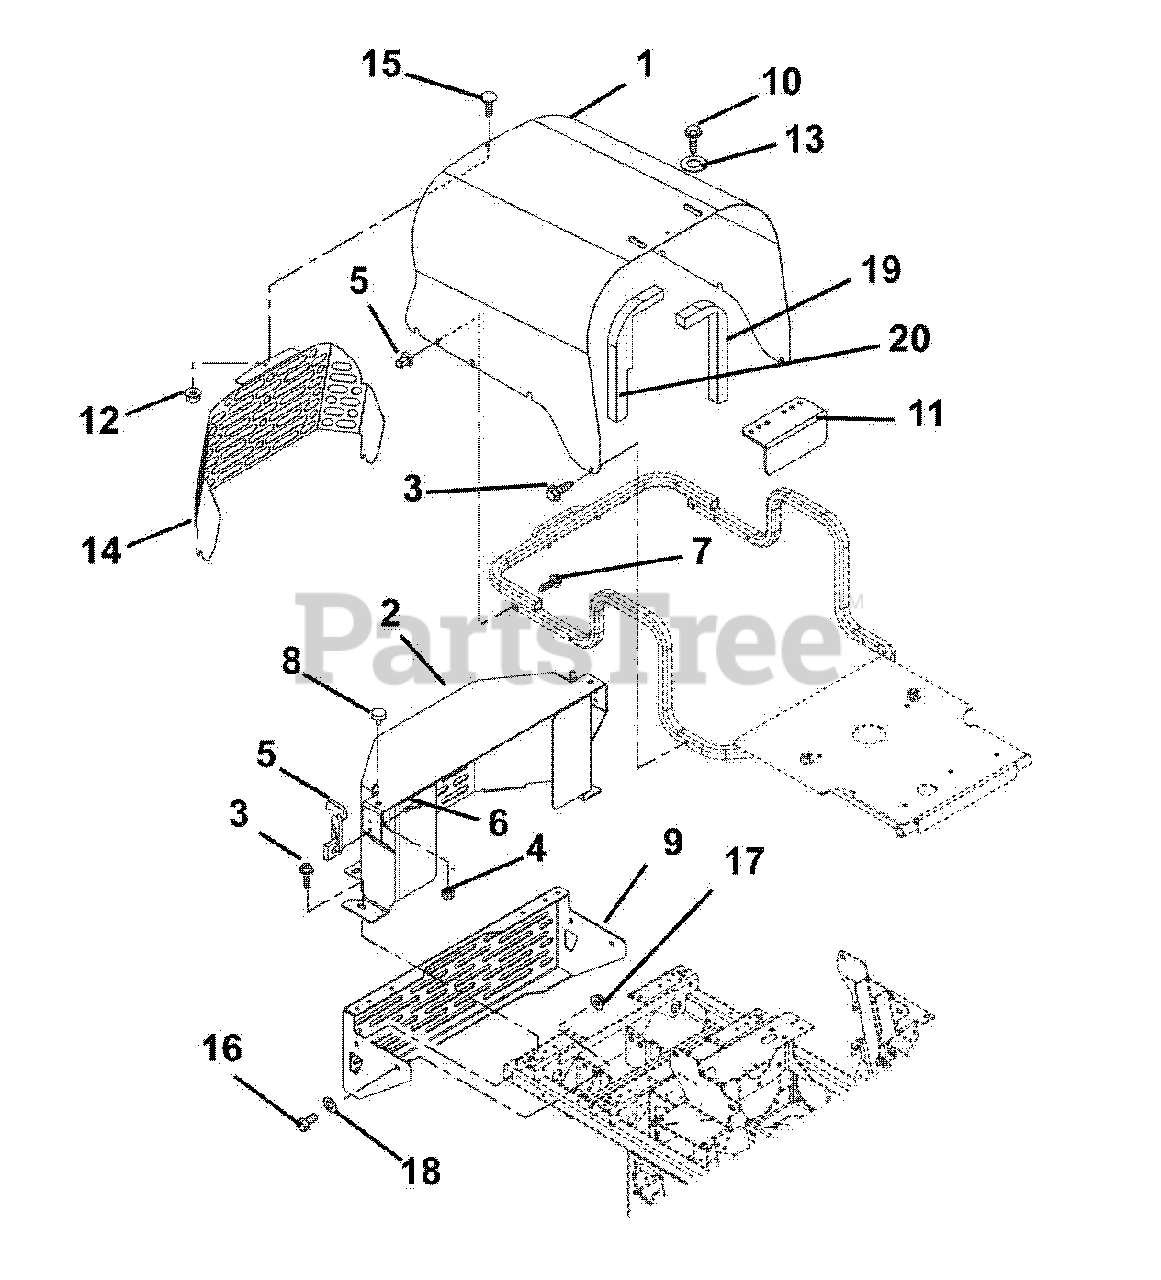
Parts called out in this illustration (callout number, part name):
2	Diesel Belt Guard
3	Screw, Tapping .38-16 x .75 Hex Washer Head
4	Nut, Spin Lock, Flange .312-18
5	Latch, Rubber
6	Screw, Machine 10-24 x .50 Hex Washer Head
7	Screw, Machine 10-24 x 1.50 Hex Washer Head
8	Bumper, Rubber
9	Bumper, Weldment, Rear Diesel
10	Screw, Tapping .25-20 x .50 Hex Washer Head
11	Guard, Radiator Cap
12	Nut, Locking Top Flange .25-20
13	Washer, Flat Steel .281 x .62 x .065
14	Guard, Hood
15	Bolt, Round Head Square Neck .25-20 x .50 Grade 5
16	Bolt, Hex .38-16 x 2.75 Grade 5
17	Nut, Locking Top Flange .38-16
18	Washer, Flat Steel .406 x .812 x.065
19	Dam, Left Side Foam Air
20	Dam, Right Side Foam Air
